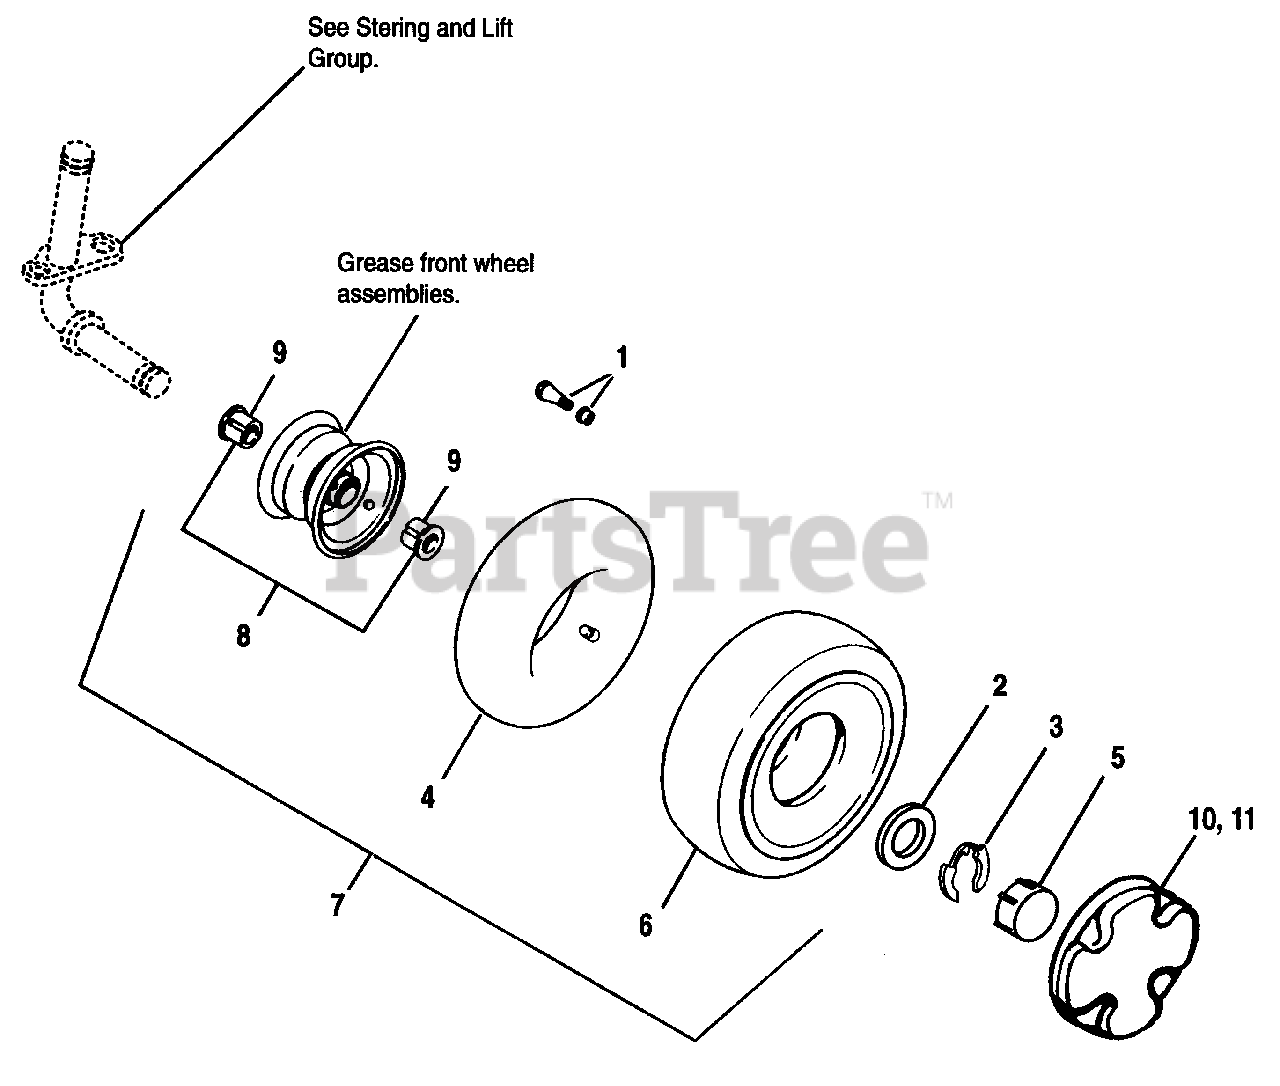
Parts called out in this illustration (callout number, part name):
1	VALVE STEM & CAP
2	WASHER, 3/4 (Qty. 10 used on hydro models)
4	TUBE, Front Wheel, 4.10/3.50 x 6
5	CAP, Threaded
6	TIRE, Front Wheel, 13 x 5.00-6
7	FRONT WHEEL & TIRE ASSY., 13 x 5.00-6, Metallic Gray (Incl. Ref. Nos. 1, 4, 6 & 8)
8	FRONT WHEEL ASSY., 13 x 5.00-6, Metallic Gray (Incl. Ref. No. 9)
9	BUSHING, Metal, 7-21/32 I.D.
10	HUB CAP, 6", Smooth
11	HUB CAP, 6", Scalloped
